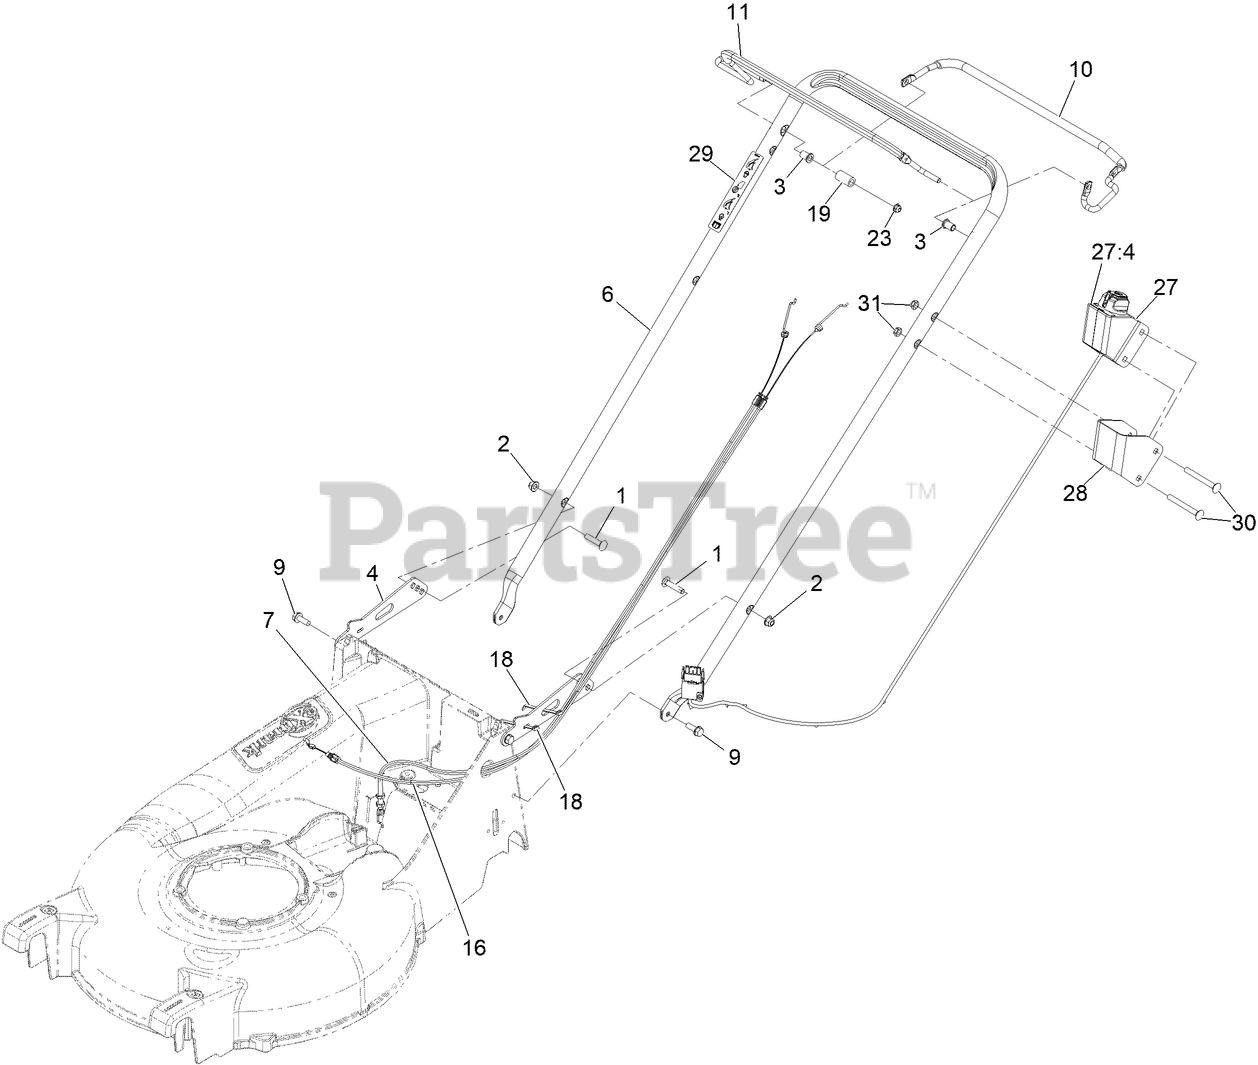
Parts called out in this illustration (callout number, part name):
1	BOLT-CARR
2	NUT-HF, NI
3	BUSHING-HANDLEBAR
4	BRACKET,HANDLEBAR
6	HANDLEBAR-EC21
7	CABLE, DRIVE EC21
9	SCREW-TAPTITE
10	BAIL-DRIVE COATED
16	CABLE-OPC
18	TIE-CABLE
27	ASM-STARTER SWITCH
27:4	STARTER BUTTON SERVICE ASM
28	GUARD-SWITCH
29	DECAL-CONTROLS (60V START)
30	SCREW-CARR
31	NUT-LOCK, NI
